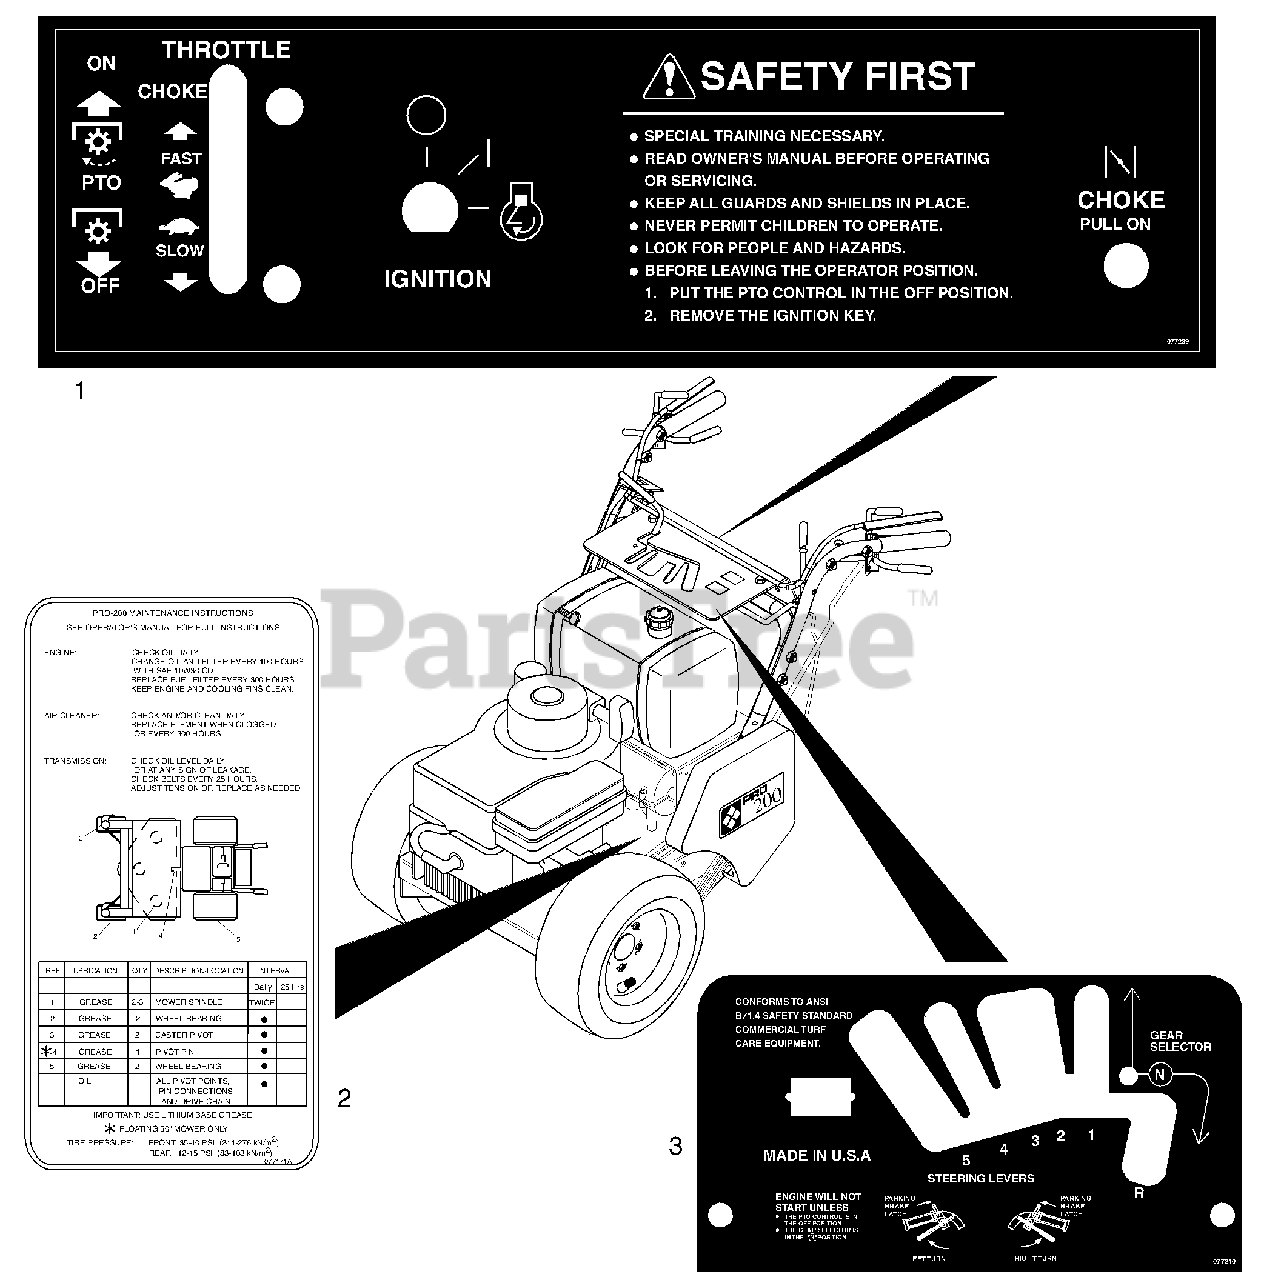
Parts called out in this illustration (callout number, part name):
1	Decal, Pro-200 Instrument Panel
2	Decal, Pro-200 Maintenance
3	Decal, Pro-200 Instrument Panel
4	Decal, Pro-200 14hp
4	Decal-Pro-200 18 H.P.
